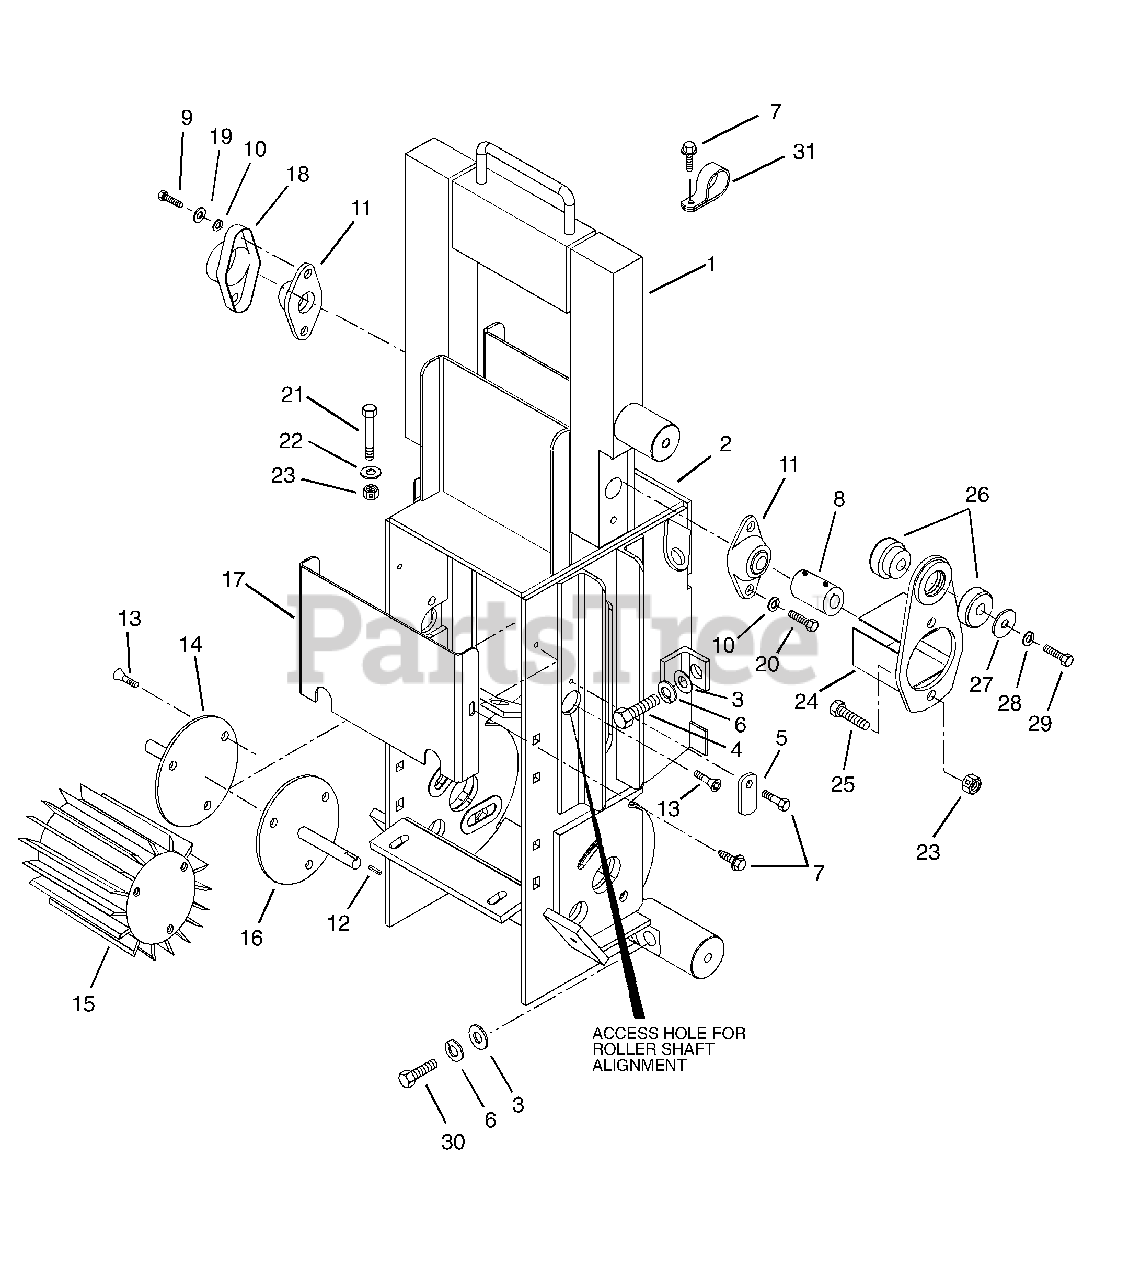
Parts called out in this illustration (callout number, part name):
1	Saddle-Weldment Assembly
2	Feed Box Weldment
3	Washer-Flat-Steel .531 x 1.06 x .095
4	Bolt-Hex .50-13 x 1.00 Grade 5
5	Enclosure
6	Washer-Lock .50 x .125
7	Screw-Tapping .25-20 x .50 Hex Washer Head
9	Bolt-Hex .44-14 x 1.50 Grade 5
10	Washer-Locking .44 x .109
11	Bearing Flange
12	Key-Square
13	Bolt-Flat Socket Head .50-13 x 1.0
14	Roller Shaft - Left
16	Roller Shaft - Right
17	Cover-Feed Box
18	Cover-Bearing Feed Roll
19	Washer-Flat-Steel .505 x 1.00 x .062
20	Bolt-Hex .44-14 x 1.25 Grade 5
21	Bolt-Hex .50-13 x 2.00 Grade 5
22	Washer-Flat-Steel .531 x 1.06 x .095
23	Nut-Locking-Center .50-13
24	Torque Arm Weldment
25	Bolt-Hex .50-13 x 1.50 Grade 5
26	Rubber Bushings
27	Washer-Flat-Steel .50 x .25 x .13
28	Washer-Locking .50 x .125
29	Bolt-Hex .50-13 x 3.00 Grade 5
30	Bolt-Hex .50-13 x 2.75 Grade 5
